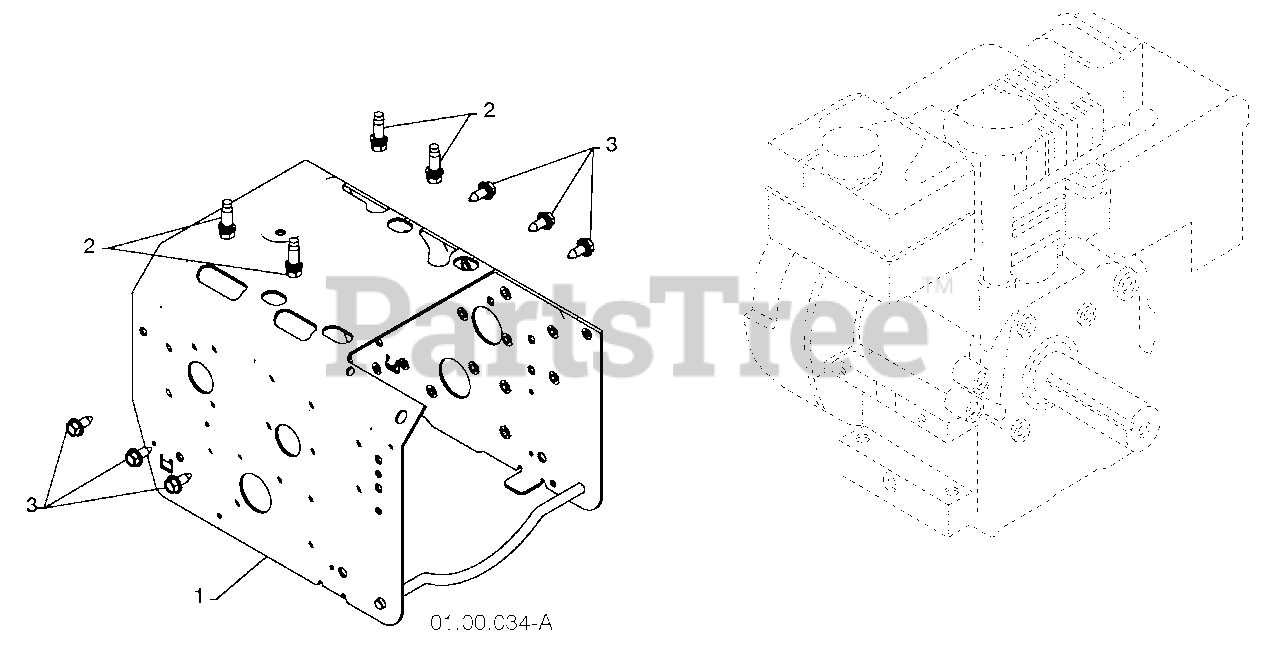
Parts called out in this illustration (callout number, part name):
1	FRAME
2	BOLT 3/8-16
3	SCREW 5/16-18 X .750
